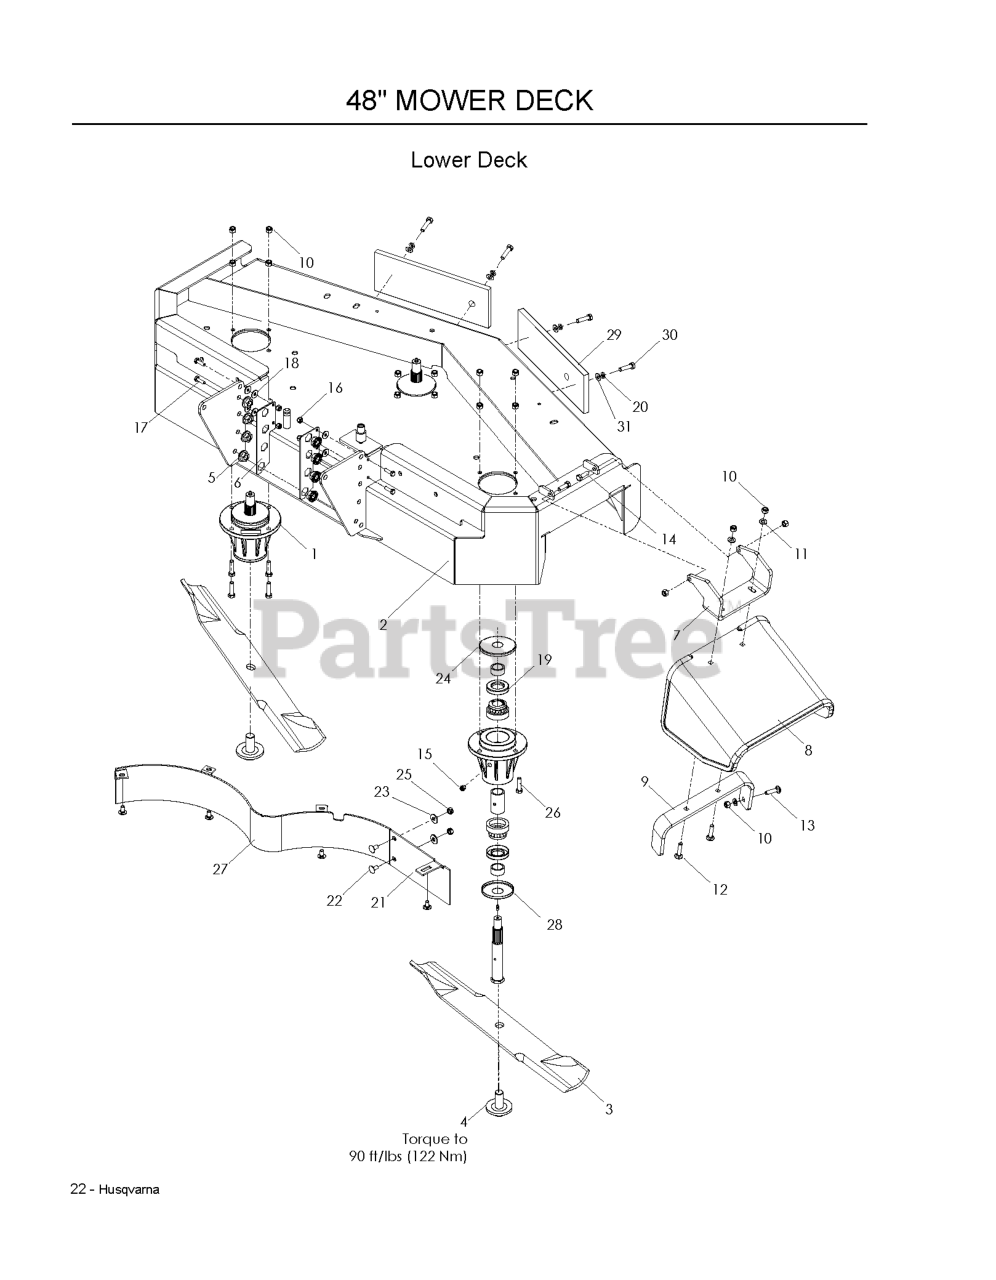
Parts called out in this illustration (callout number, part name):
1	HOUSING ASM, 72
2	DECK SVC W/DECALS WH4818
3	BLADE OEM 16 1/4"
4	BLADE BOLT/WASHER
5	NUT FLANGE 1/2-13 GR 5
6	PLATE NUT - PAINTED
7	HINGE CHUTE - BLACK
8	CHUTE, RUBBER DISCHARGE WB
9	BRKT, REINF-CHUTE WB
10	NUT 5/16 NYLOC
11	FLAT WASHER 5/16 SAE
12	RHSNB 5/16-18 X 1-1/2 GR 5 ZD
13	BOLT, CARRIAGE 5/16X1-1/4
14	HCS 5/16C X 1
16	NUT.1/4-20.HEX.NYLOC.ZD
17	HCS 1/4-20X7/8 GR5
18	WASHER 1/4 FLAT
19	SHAFT SEAL
20	WASHER 1/2" SPLIT LOCK
21	CENTER BAFFLE 48"
22	CARRIAGE BOLT 5/16C X 5/8"
23	WASHER 5/16 FLAT
24	TOP DUST CAP
25	NUT 5/16C CENTERLOCK
26	HCS 5/16C X 1 1/4
27	BAFFLE WLDT, BLACK
28	BOTTOM DUST CAP
29	WEIGHT, COUNTER, ORANGE
30	HCS 1/2-13 X 1-1/2 GR 5 ZD
31	WASHER 1/2" FLAT
